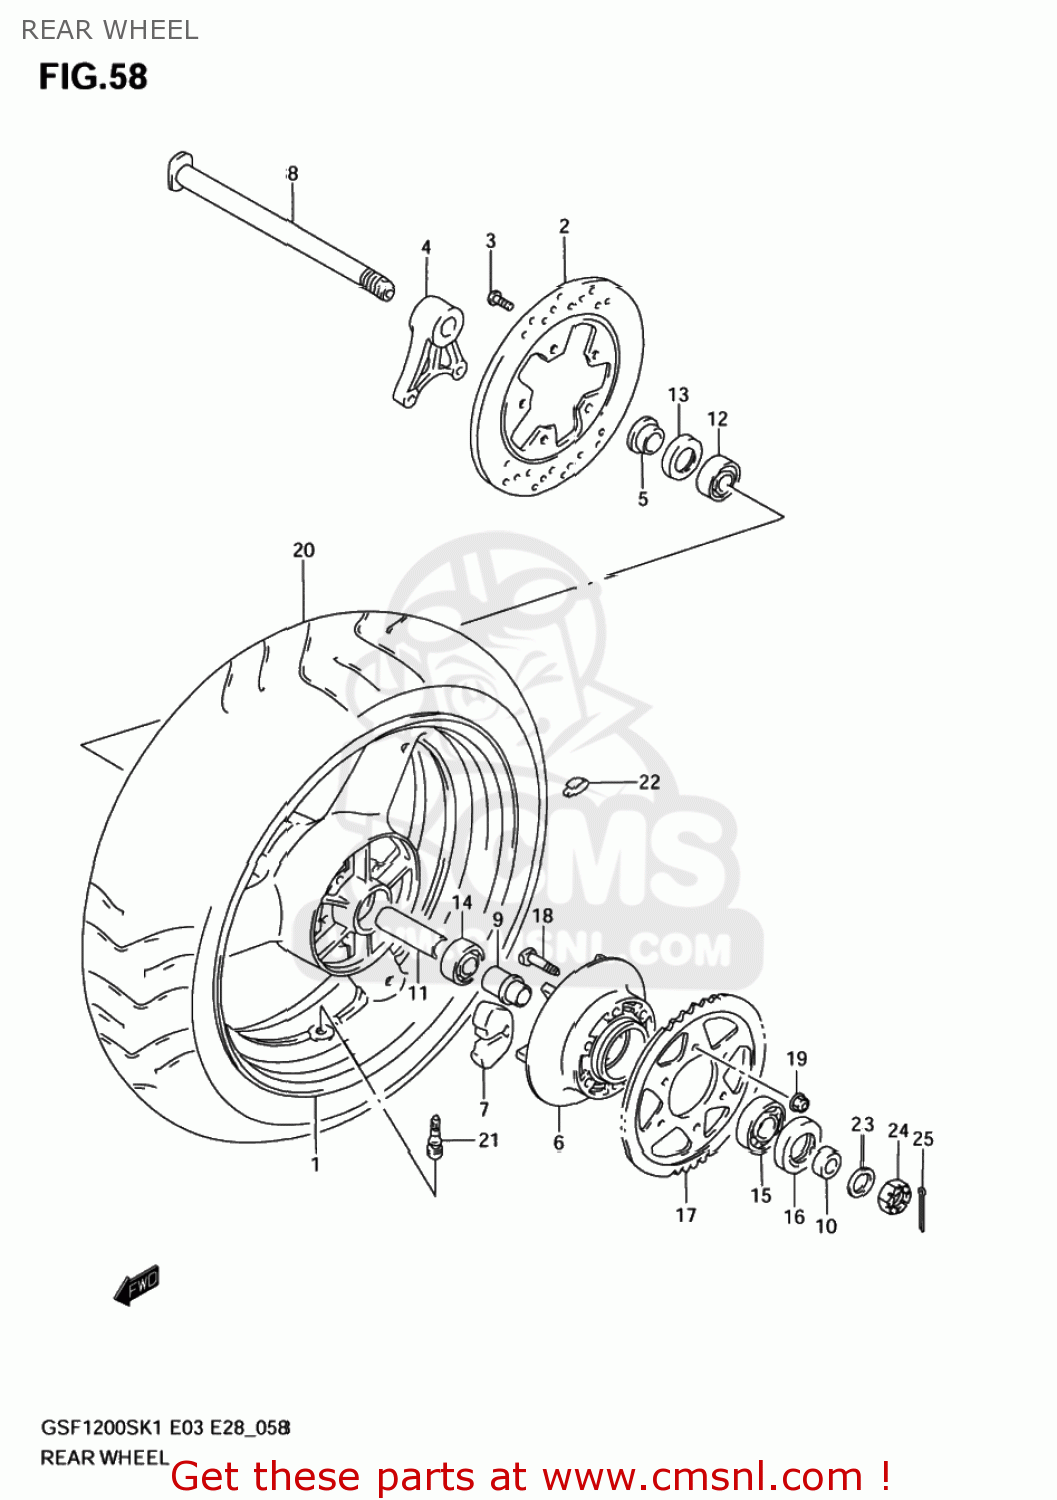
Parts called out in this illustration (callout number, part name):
1	WHEEL,REAR,17X
2	DISC,RR BRAKE
3	BOLT 8X33
4	BRACKET,RR CALIPER
5	SPACER,RR AXLE,R
6	DRUM,RR SPROCKET
7	ABSORBER,RR HUB SHOCK
8	AXLE,RR
9	RETAINER,RR HUB BEARING
10	SPACER,RR AXLE,L
11	SPACER,RR WHEEL HUB BEARING
12	BEARING(20X47X14)
13	SEAL,OIL(28X47X7)
14	BEARING(20X47X14)
15	BEARING(25X62X17)
16	SEAL,OIL(35X62X8)
17	SPROCKET,RR(NT:45-530)
18	BOLT
19	NUT
20	TIRE COMP.RR.18
21	VALVE ASSY,WHEEL RIM(TR412)
22	BALANCER,WHEEL(10G)
23	WASHER(18.5X28X2.6)
24	NUT
25	PIN, COTTER
